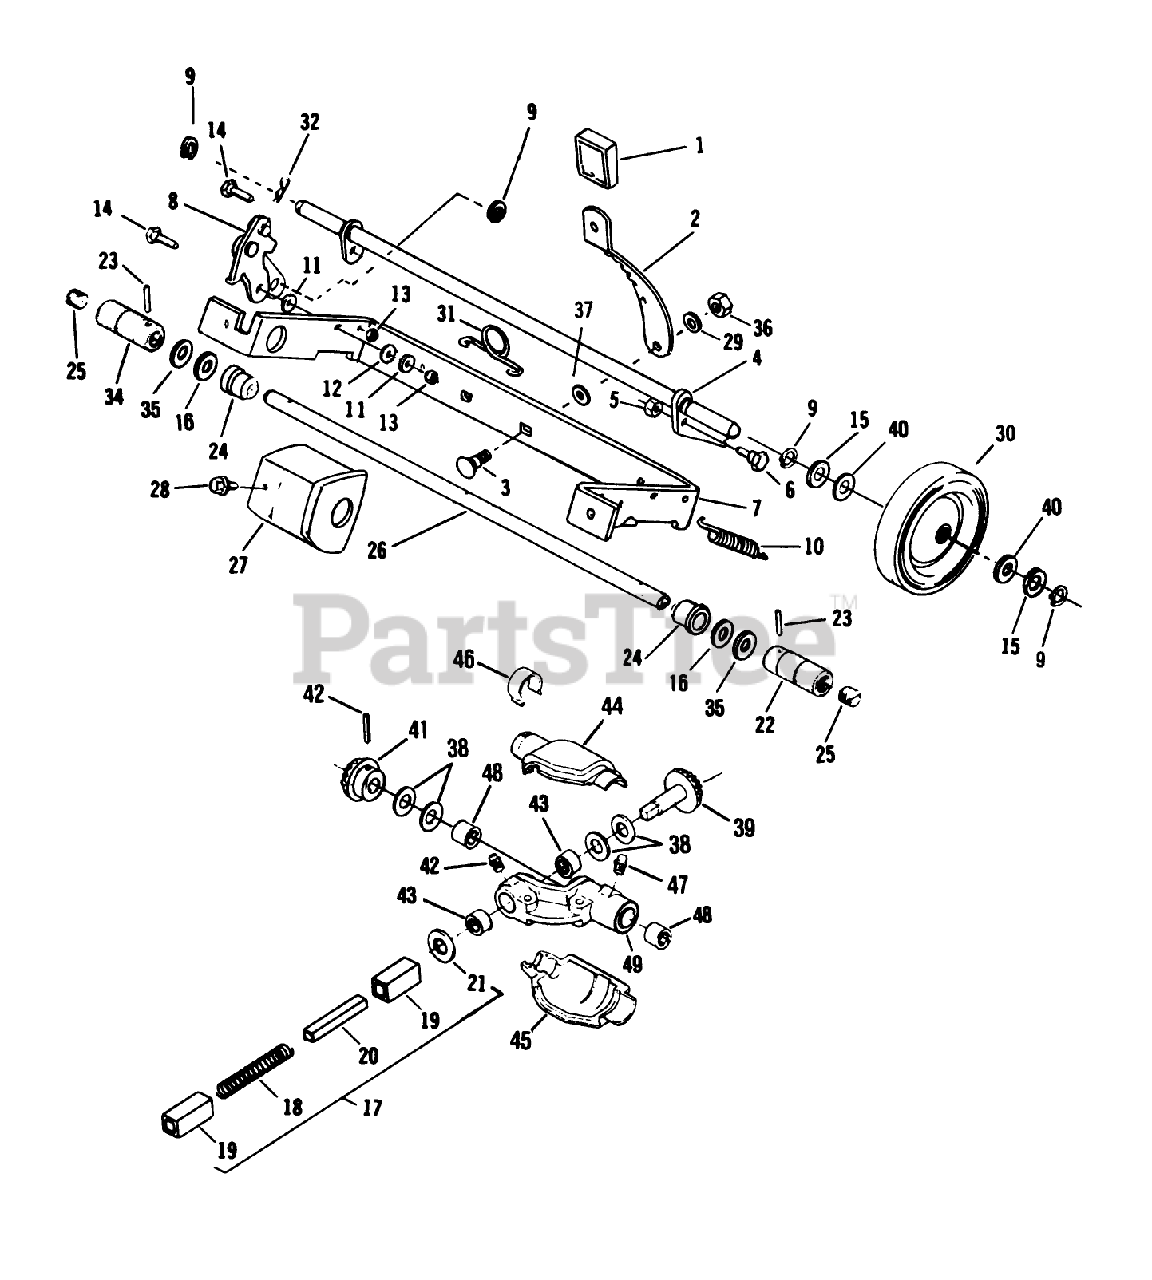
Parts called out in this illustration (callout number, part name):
2	LEVER
4	AXLE & TORQUE LUG ASM
5	LOCKNUT E
6	BOLT RB&W
7	BRACKET *GREEN
8	CLUTCH AY ARGO
9	RET RING
10	SPRING
11	WASHER S
13	STOP NUT
14	BOLT RB&W
15	SPACER
16	THRUST WASHER
18	SPRING
19	BUSHING BKWY
21	THRUST WASHER
22	ROLLER-LEFT
24	SLEEVE &BEARING AY
25	GREASE PLUG
26	DRIVE SHAFT & TAG
29	WASHER S
31	SPRING N.A.S
33	RET RING
36	LOCKNUT E
37	WASHER SPRING LAR
38	THRUST WASHER
39	GEAR BEST
40	WASHER
41	GEAR ADVANCE
42	ROLL PIN
44	GEAR COVER UPPER
47	**FITTING LINCOLN
